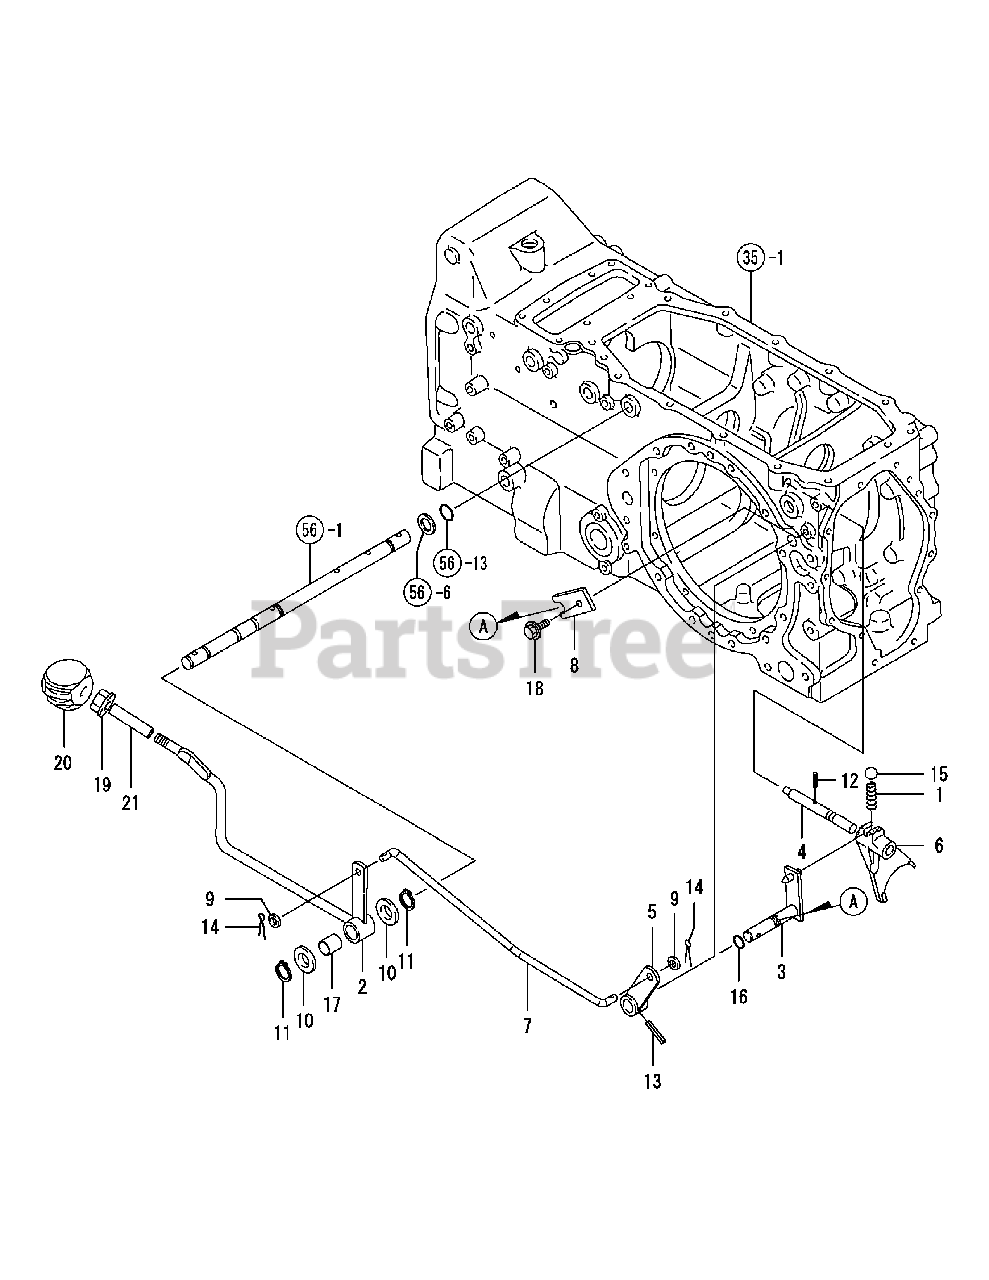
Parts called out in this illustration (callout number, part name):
1	SPRING, FORK LOCK
4	SHAFT, P.T.O FORK
5	ARM, P.T.O CHANGE
6	FORK, P.T.O SHIFT
9	WASHER 10,POLISHED
10	WASHER 20,POLISHED
12	SPRING PIN 6X25
13	SPRING PIN 6X32
14	COTTER PIN 2.5X20
15	BALL 1/4, STEEL
16	O-RING 1A P-12.5
18	BOLT M 8X 16 PLATED
19	NUT W/WASHER 10
